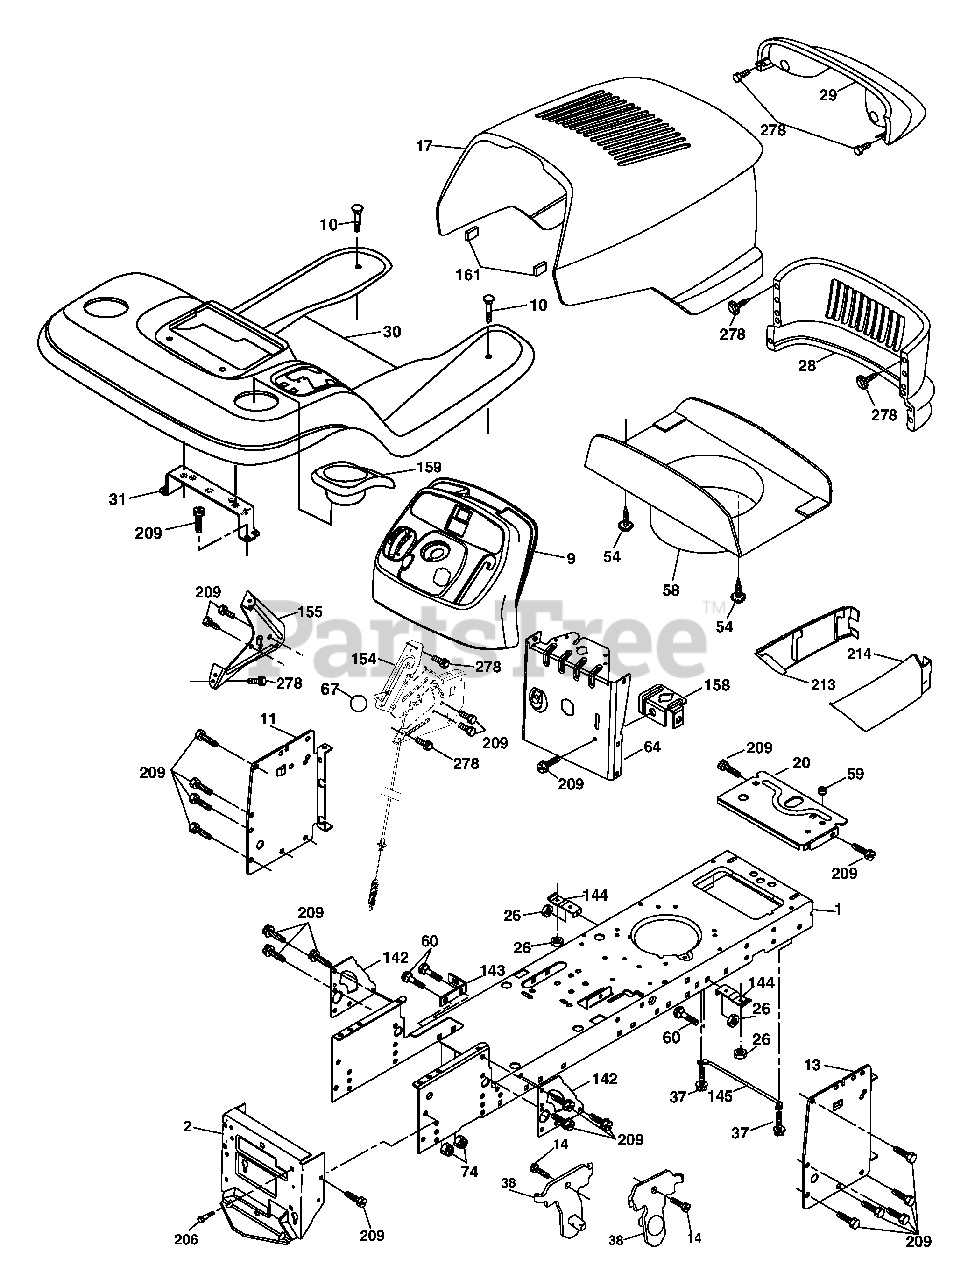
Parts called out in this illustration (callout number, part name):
1	Chassis
2	Drawbar
9	Dash
10	Bolt Carriage 3/8-16 x 1
11	Panel Dash Lh
13	Panel Dash Rh
14	Screw Thdrol 3/8-16 x 1/2
17	Hood
20	Plate Battery
26	Nut Lock Hex W/Ins 3/8-16 unc
28	Grille
29	Lens Bar
30	Fender Footrest
31	Bracket Fender
37	Screw Thdrol 6/16-18 x 1/2 TYT
38	Bracket Asm Pivot Mower Rear
54	Screw WSHD Hex 10-32 x 5/8
58	Duct Air
59	Bushing
60	Bolt RDHD Sqnk 3/8-16 unc x 3/4
64	Dash Lower STLT
67	Knob
74	Nut Crownlock 3/8-16 unc
142	Plate Reinforcement STLT
143	Bracket Swaybar Chassis
144	Bracket Footrest Step-thru
145	Rod Pivot Chassis/Hood
154	Bracket Clutch Asm
155	Bracket Dash LH
158	Bracket Parking Brake
159	Cupholder
161	Bumper Hood
206	Bolt Shoulder 5/16-18
209	Screw Hexwsh Thdr 3/8-16 x 3/4
213	Skirt Grille LH
214	Skirt Grille RH
278	Screw 10 x 3/4 Single Lead-Hex
